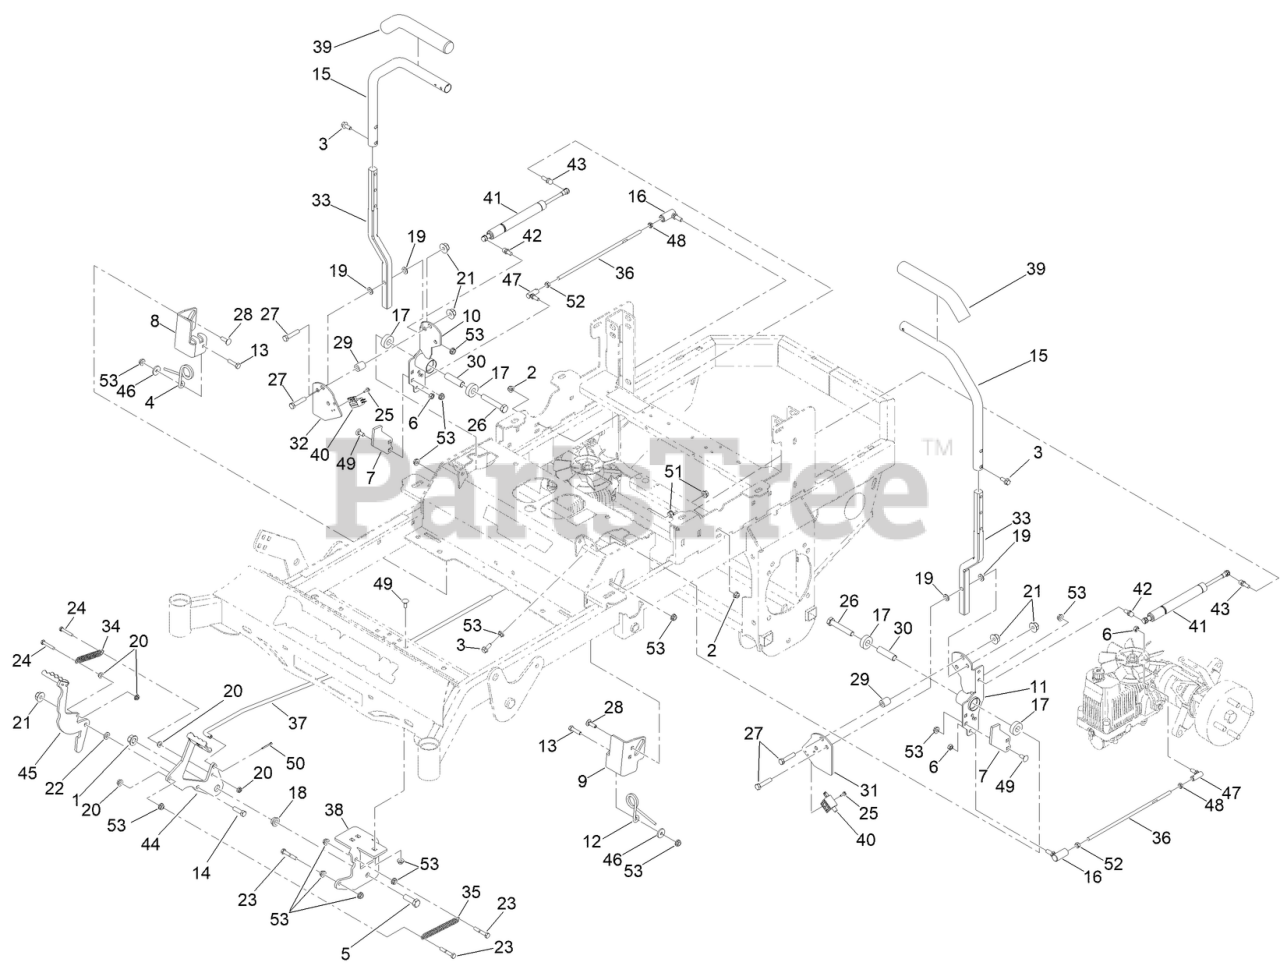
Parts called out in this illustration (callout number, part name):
1	NUT-LOCK
2	NUT-HF, NI
3	SCREW-HHF
4	SPRING-TORSION
5	SCREW-HH
6	5/16-24 NYL INS L/N GR.8 ZC/YEL
7	REVERSE DETENT KICK PLATE
8	REVERSE DENTENT SPRING BASE (RH)
9	REVERSE DENTENT SPRING BASE (LH)
10	MOTION CONTROL BRKT
11	MOTION CONTROL BRKT
12	SPRING- LT REVERSE DETENT
13	SCREW-HH
14	SCREW-HH
15	MOWER DRIVE HANDLE TUBE ABC
16	CONTROL ARM ROD END LT
17	5/8IN ID X 1-3/8IN OD X 7/16IN THK BRG
18	1/2IN ID X 3/4IN OD X 3/8IN FLANGE BUSH
19	3/8 X 3/4 BRONZE WASHER
20	1/4-20 HEX FLANGE NUT
21	3/8-16 NYLON INSERT FLANGE L/NUT YZ
22	3/8 ID X 3/4 OD X .125 THK BRONZE WASHER
24	1/4-20 X 1-1/4 HEX C/S GR 2 ZINC
25	8-32 X 1/2 IND. HWH SLOT TYPE F TCS ZINC
26	1/2-13 X 3 HEX C/S GR 5 ZINC W/LOCTITE
27	3/8-16 X 1-3/4 HEX C/S GR 2 ZINC
28	5/16-18 X 1 CARRIAGE BOLT GR 8 YZ
29	MWR DRIVE ARM SPACER
30	MWR DRIVE ARM HUB / DECK LIFT ARM SPACER
31	LT CONTROL ARM LIMIT SWITCH PLATE PAINT
32	RT CONTROL ARM LIMIT SWITCH PLATE PAINT
33	HEIGHT ADJUSTABLE CONTROL ARM
34	MWR BRAKE PEDAL RELEASE SPRING
35	2020 MWR BRAKE PEDAL TENSION SPRING
36	TRANS DRIVE ARM LINKAGE STANDARD TRANS
37	MWR BRAKE LINKAGE
38	MWR FRAME BRAKE MTG BRKT PAINT
39	CONTROL ARM HANDLE GRIP
40	NO PLUNGER LIMIT SWITCH
41	CONTROL ARM DAMPER
42	5/16-18X1.286 DAMPER BALL STUD (.562 TL)
43	5/16-18X1.286 DAMPER BALL STUD (.562 TL)
44	MWR BRAKE LOCK LEVER ASSY PAINTED
45	MWR BRAKE UNLOCK LEVER ASSY PAINTED
46	STRIKER POST FENDER WASHER
47	BALLJOINT-RH (W/GROMMET)
48	NUT-JAM
49	BOLT-CARR
50	PIN-COTTER
51	NUT-HHF, WHIZ
53	NUT-HF
